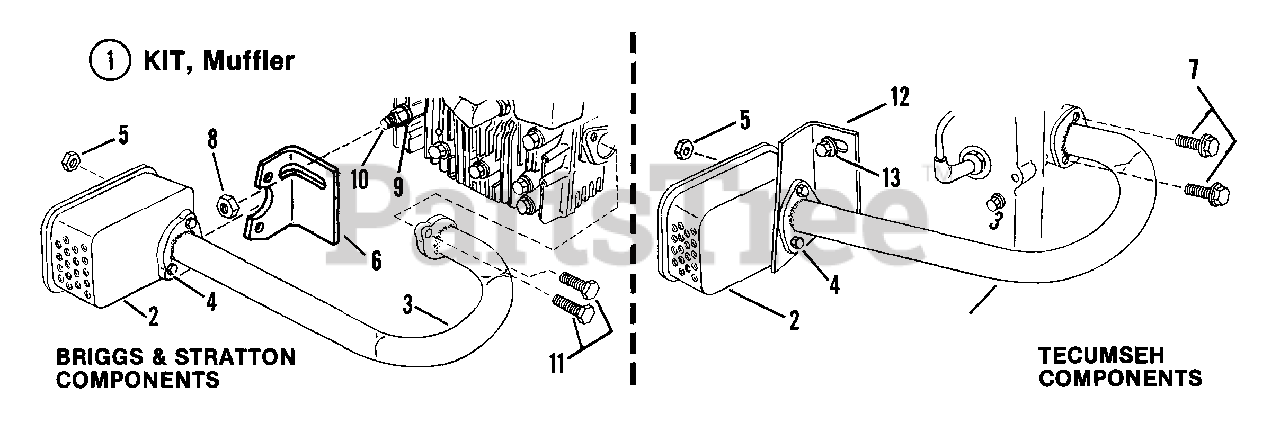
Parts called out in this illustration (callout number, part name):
1	KIT, Muffler
2	MUFFLER
3	TUBE, Exhaust
4	CAPSCREW, 5/16Cx3", Hex Head
5	LOCKNUT, 5/16-18 Hex Flange
6	MOUNTING
7	SCREW, 5/16-18x3/4" Hex Flange
8	NUT, 5/16-18 Hex
9	WASHER, Flat
10	STUD, Cylinder Head
11	CAPSCREW, 1/4-20x5/8" Hex Head
12	CLIP, Mounting
13	SCREW, 1/4Cx5/8" Self-Tapping
